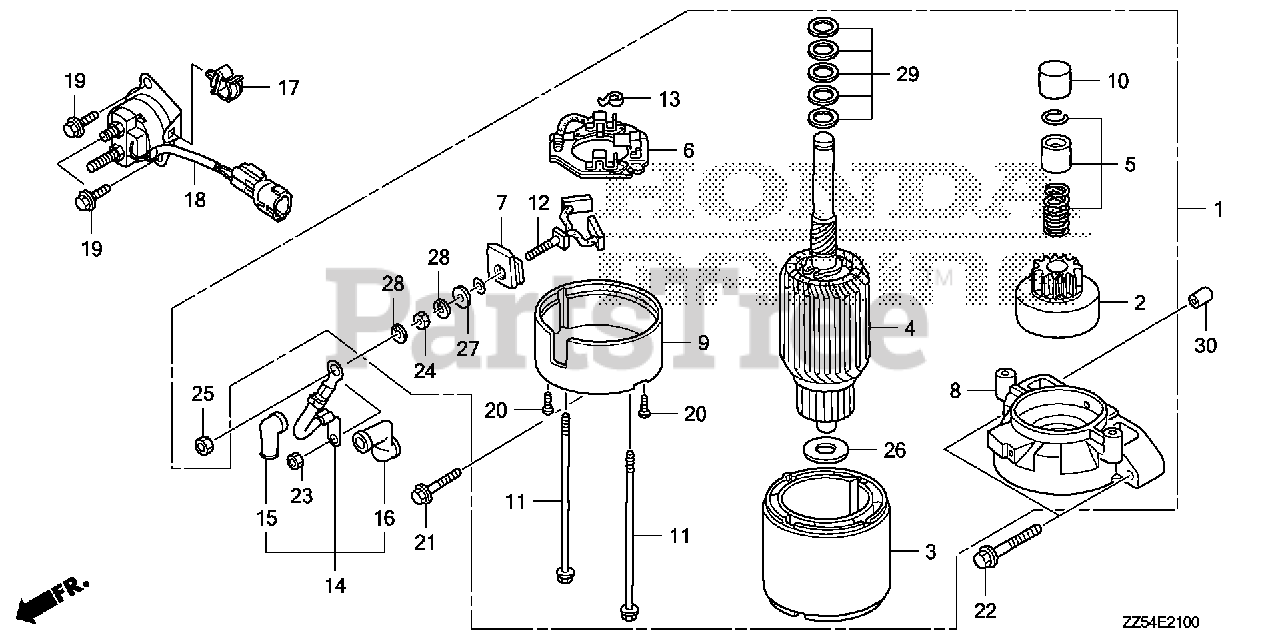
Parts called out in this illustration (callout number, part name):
1	STARTER MOTOR ASSY.
2	CLUTCH, OVERRUNNING
5	STOPPER SET, PINION
6	HOLDER, BRUSH
8	BRACKET, FR.
9	BRACKET, RR.
10	CAP, STOPPER
11	BOLT, THROUGH
13	SPRING, BRUSH
14	WIRE, MAGNETIC SWITCH
15	COVER, STARTER MOTOR TERMINAL
16	COVER, MAGNETIC SWITCH TERMINAL
17	CLAMP, WIRE
18	SWITCH ASSY., STARTER MAGNETIC
19	BOLT, FLANGE (6X14) (CT200)
20	SCREW (4MM)
21	BOLT, FLANGE (6X28)
22	BOLT, FLANGE (8X45)
23	NUT, HEX. (6MM)
26	WASHER, RR.
27	WASHER (1)
28	WASHER (2)
29	WASHER SET, THRUST
30	PIN A, DOWEL (10X16)
